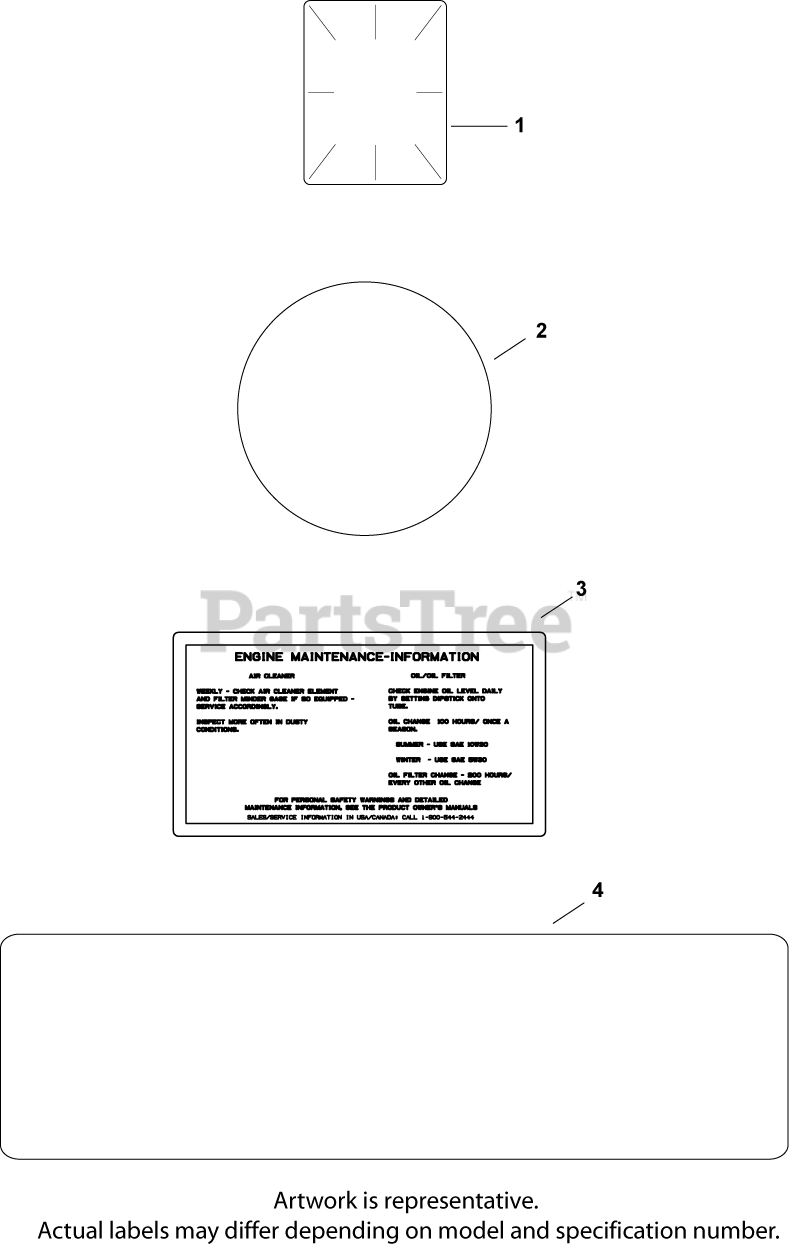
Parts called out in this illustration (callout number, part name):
1	DECAL, CLEAR LAMINATE USE 25 113 70-S
2	DECAL, GRASS SCREEN USE 24 113 499-S
3	DECAL, AIR CLEANER - (#DSC)
4	DECAL, 25 HP - DISCONTINUED
